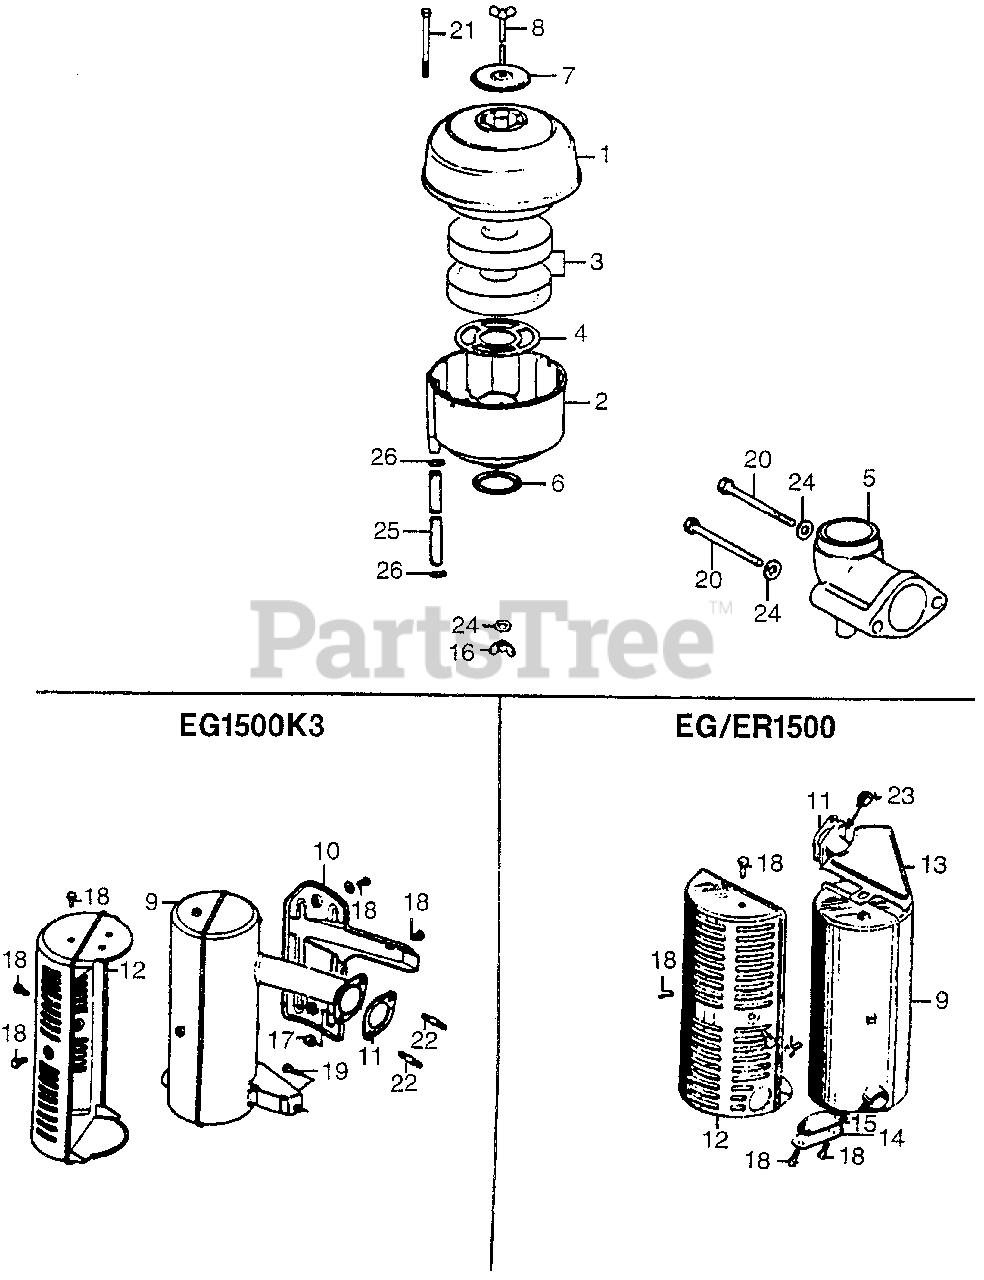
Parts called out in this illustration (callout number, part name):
1	BODY, CLEANER
2	PAN, AIR CLEANER OIL
3	ELEMENT, AIR CLEANER
4	GRID, AIR CLEANER
5	ELBOW, AIR CLEANER
6	GASKET, IN. ELBOW (NOT AVAILABLE)
7	CAP, AIR CLEANER
8	BOLT, AIR CLEANER
9	MUFFLER (NOT AVAILABLE)
9	MUFFLER
10	SEPARATOR, MUFFLER
11	GASKET, MUFFLER
12	PROTECTOR, MUFFLER
17	NUT, HEX. (6MM)
18	BOLT, HEX. (6X8)
18	BOLT, HEX. (6X6)
19	BOLT, HEX. (6X16)
20	BOLT, HEX. (6X60)
22	BOLT, STUD (6X18)
24	WASHER, PLAIN (6MM)
25	BULK HOSE, FUEL (8X1000) (8X200)
26	CLIP, TUBE (B12.5)
